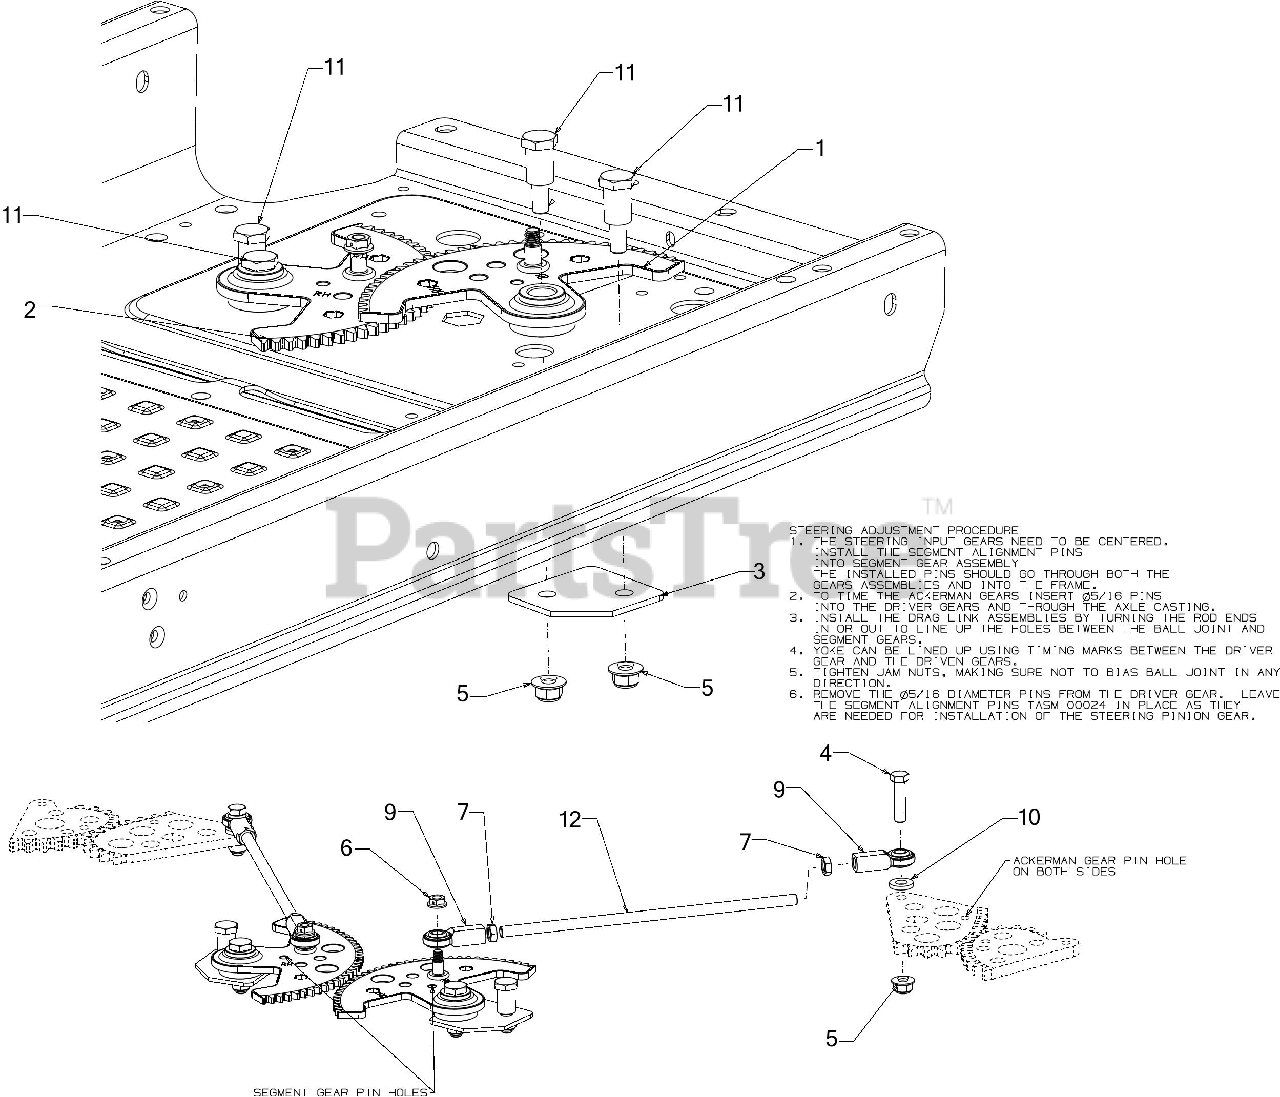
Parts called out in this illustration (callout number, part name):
1	STEERING GEAR ASSEMBLY (RH)
2	STEERING GEAR ASSEMBLY (LH)
3	STEERING SUPPORT PLATE
4	SCREW 3/8-16 x 1.50
6	FLANGE NUT
7	HEX JAM NUT 3/8X24
9	BALL JOINT (RH)
10	FLAT WASHER
11	SHOULDER SCREW .625 x .875 x 3/18
12	STEERING DRAG LINK
